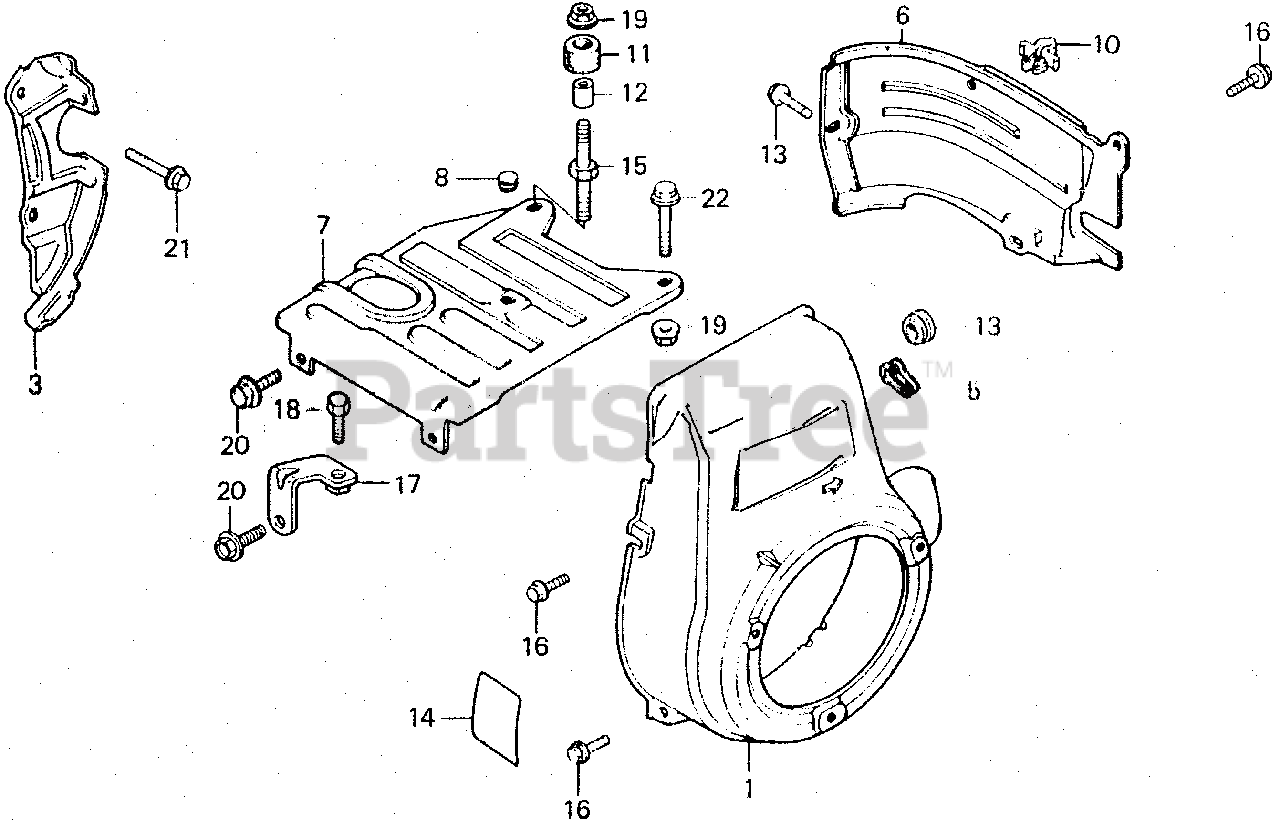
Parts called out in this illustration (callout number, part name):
1	COVER, FAN *R8* (BRIGHT RED)
4	PLATE, SIDE
5	GROMMET, FAN COVER
6	SHROUD *R8* (BRIGHT RED)
7	COVER, TOP *R8* (BRIGHT RED)
8	GROMMET, COVER
10	CLIP, IGNITION WIRE (8MM)
11	RUBBER, STOPPER (NOT AVAILABLE)
12	COLLAR, DISTANCE
13	GROMMET, DRAIN HOLE
14	MARK, OIL CAUTION
15	BOLT, SPECIAL HEX.
16	BOLT, FLANGE (6X12) (CT200)
17	PLATE, CLAMP
18	BOLT, HEX. (8X12)
19	NUT, FLANGE (8MM)
20	BOLT, FLANGE (8X16)
21	BOLT, FLANGE (8X20)
22	BOLT, FLANGE (8X28)
